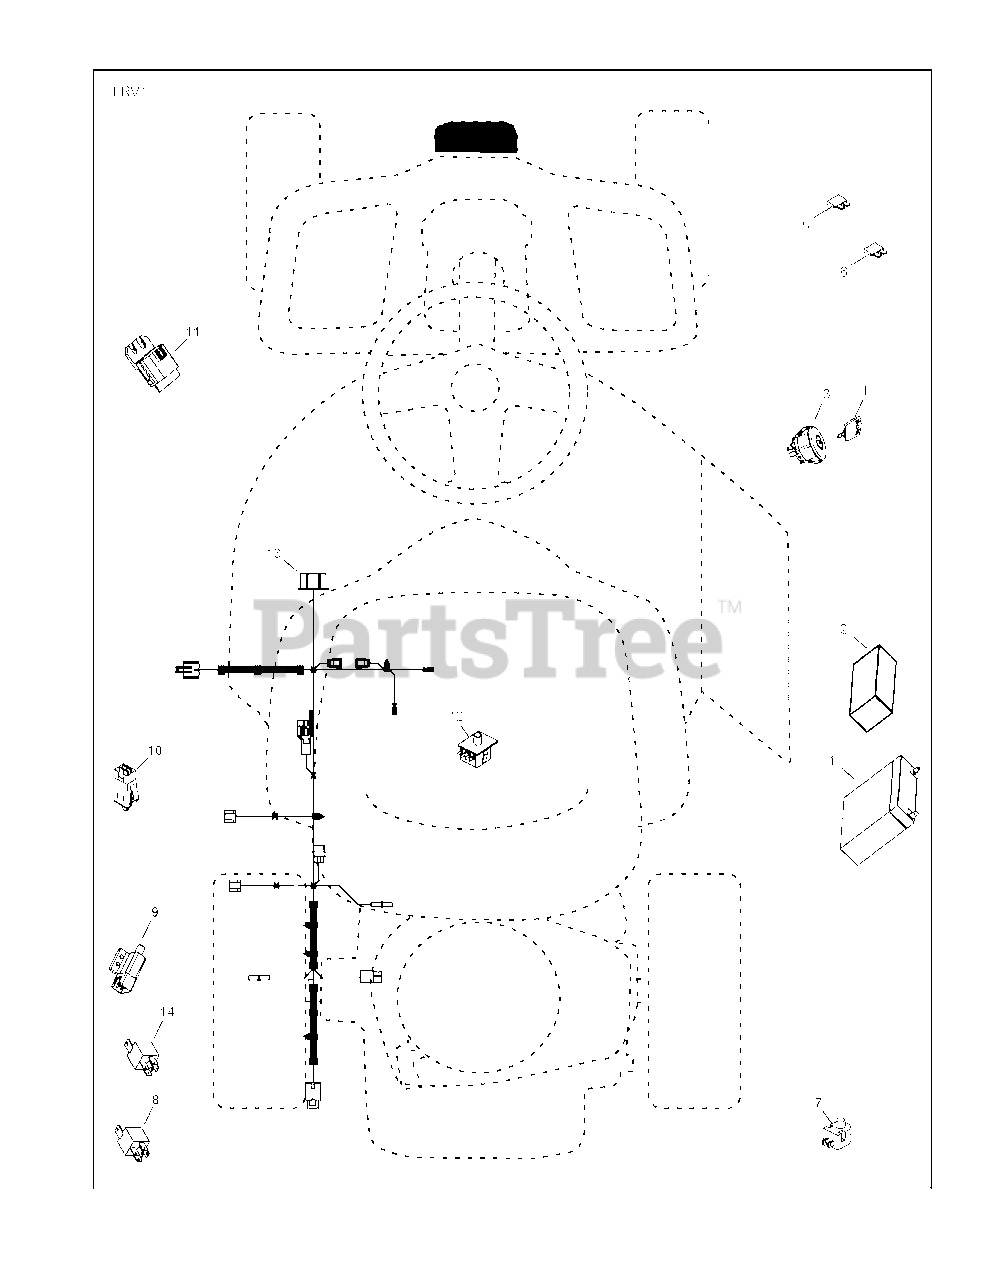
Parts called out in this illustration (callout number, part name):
1	BATTERY.2.8H.LRVA TBR
2	FOAM.POLYURETHANE
3	SWITCH.IGN.DELTA.W.LGH.ROS
4	KEY.CHAIN.BLISTER.PACK.GEN.USA
6	FUSE, 40A
7	PLUNGER SWITCH (COLOR:OLIVE)
8	RELAY, 40A
9	SWITCH INTERLOCKT
10	SWITCH INTERLOOK PUSH-IN
11	MODULE.STARTING.RECOIL.LRV
12	SWITCH.SEAT.DP W/RAMPS
13	HARNESS, IGN, ELECTSTART, LRV
14	RELAY.ASSY.T
